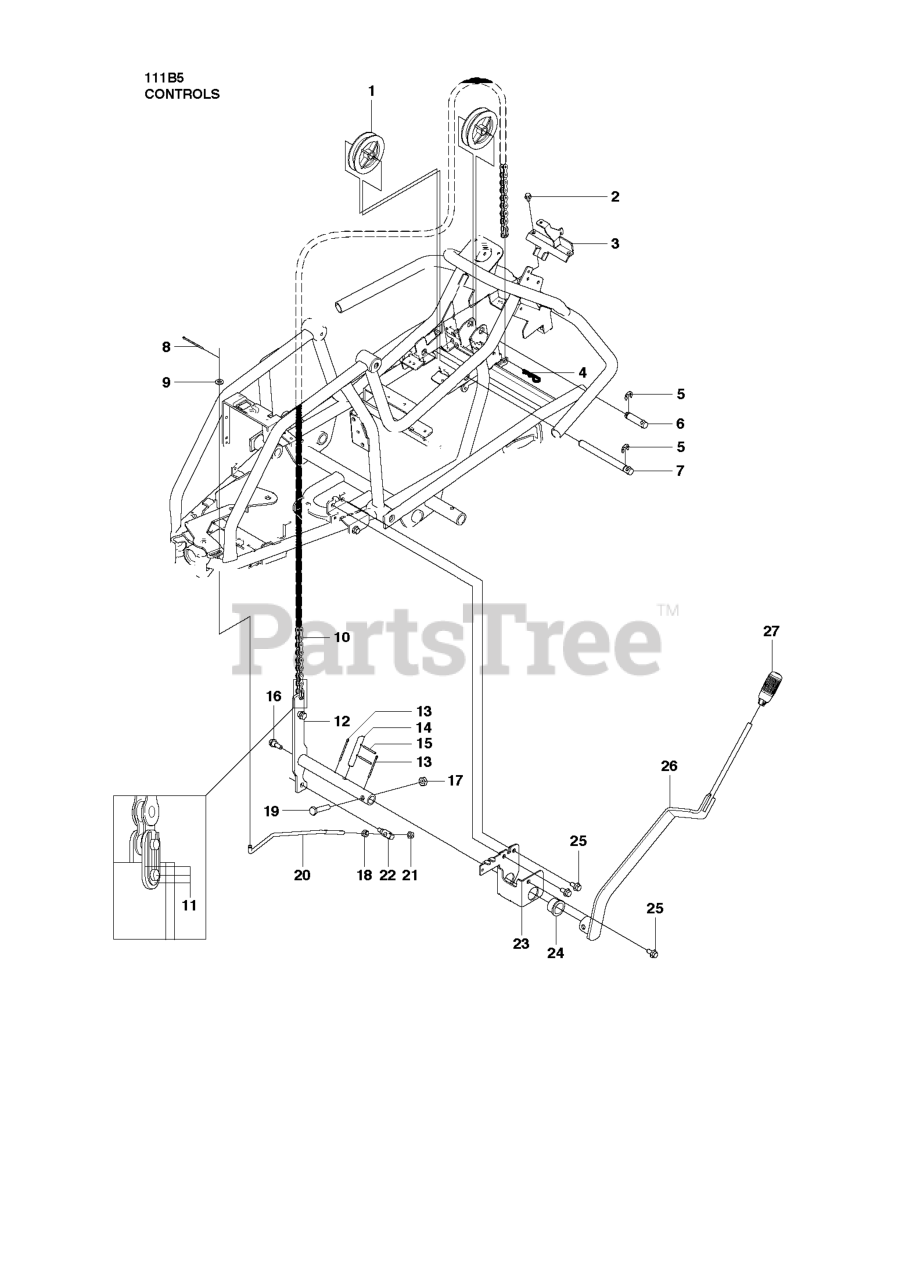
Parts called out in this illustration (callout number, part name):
9	WASHER BRB 8.4X17
13	COTTER PIN
14	RP PIN
17	NUT
18	NUT
19	REPL BY 725 25 00-71
21	LOCKNUT M8
23	BRACKET ASSY
24	BEARING FLANGE
27	GEAR STICK KNOB
